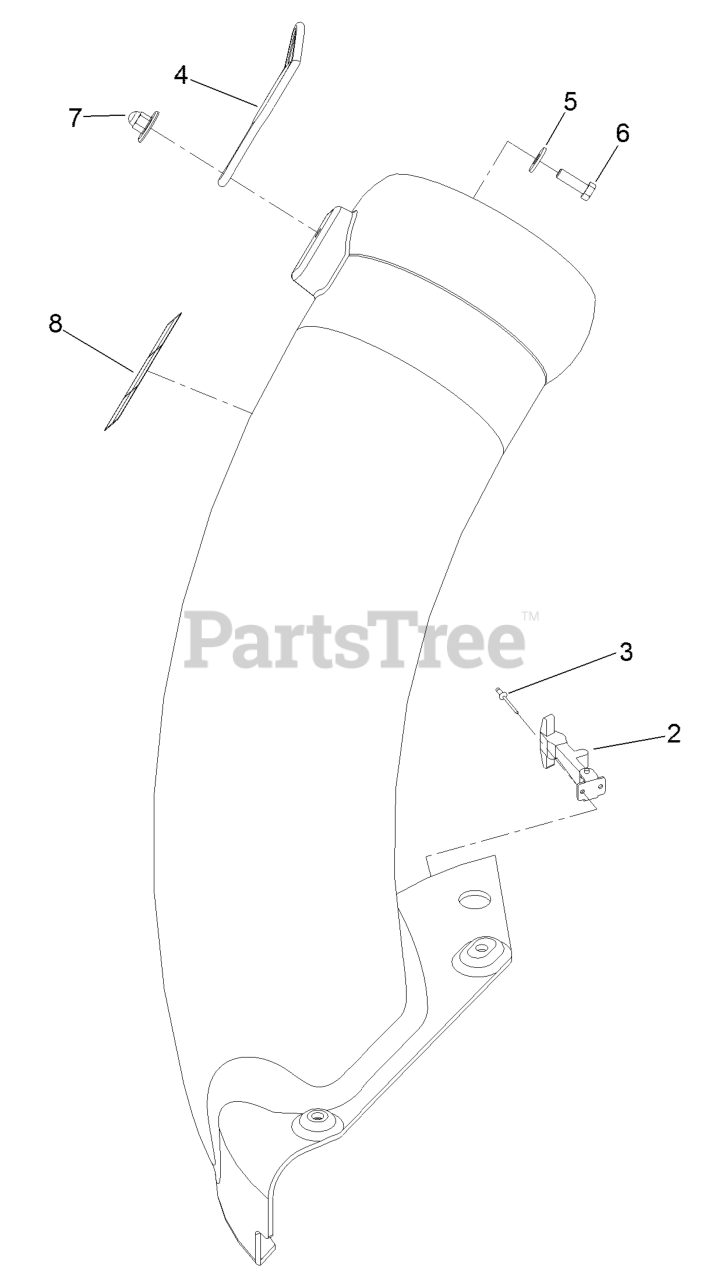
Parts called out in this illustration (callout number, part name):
2	HANDLE ASM
3	RIVET-POP
4	RETAINER-DUCT
5	WASHER-FLAT
6	SCREW-HH
7	NUT-IMPELLER
8	DECAL-DANGER
